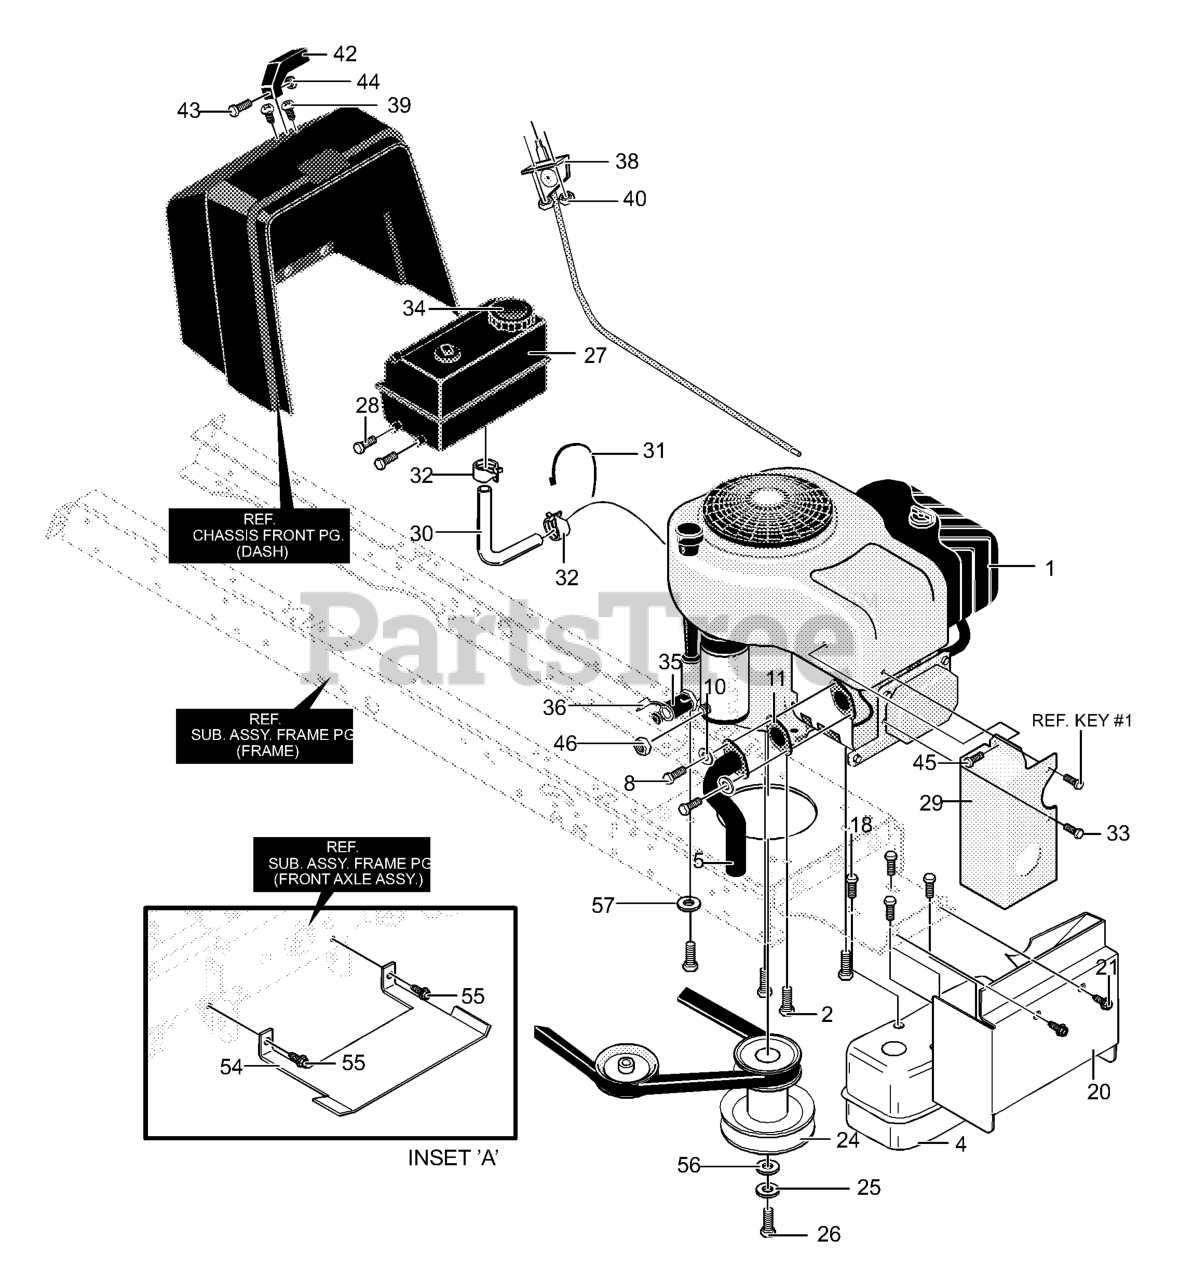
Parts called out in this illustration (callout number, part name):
1	15.5HP Engine
2	Engine Bolt
4	Muffler, Single Cylinder
5	Exhaust Tube
8	Screw, 5/16-18 x 0.75
10	Washer, Hvsptlk
11	GASKET, Exhaust
18	Screw, 1/4-20x.63
20	Heat Shield Lower Front
21	Screw, 5/16-18 x 0.75
24	Stack Pulley
25	Washer, Regsptlk
26	Screw, 7/16-20
27	Tank, Fuel 1.5 Gal.
28	Screw, 15tpx
29	Heat Shield, Side
30	Gas line 12 Inches
31	Cable Tie
32	Clamp, Fuel Clamp
33	Screw, 1/4-20x.50
34	Gas Cap
35	Oil Drain Valve Assembly
36	Cap, Oil Drain Valve
38	Throttle Control
39	Screw, 10-24x.63
40	Nut, #10-24
42	Knob, Throttle Control
43	Screw, #8-32
44	Nut, #8-32
45	Screw, 10-16x.50 Drill
46	Nut, 1/4-20
54	Shield, Anti-Dehydration
55	Screw, 5/16-18 x 0.75
56	Flatwasher, .480x1.00
57	Washer, Exlk
